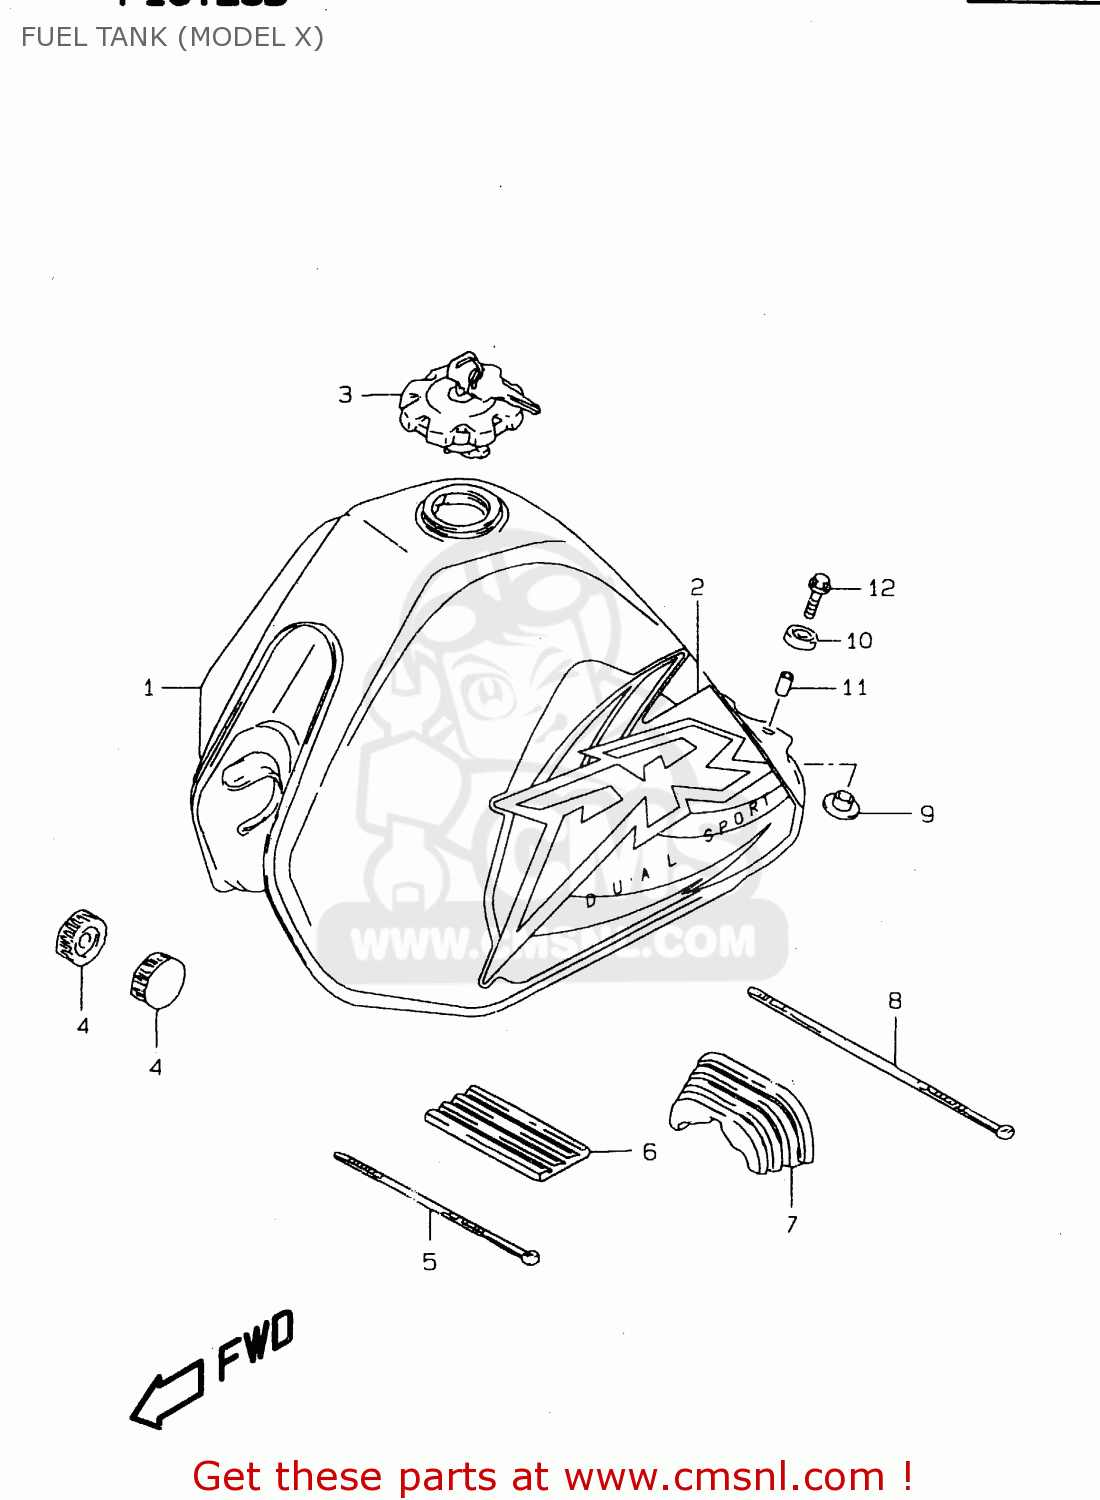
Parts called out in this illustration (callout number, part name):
1	TANK ASSEMBLY,FUEL
2	TAPE SET,FUEL TANK
3	CAP SET,FUEL TANK
4	CUSHION
5	CLAMP(L:250)
6	CUSHION,FUEL TANK UPR FR
7	CUSHION,FUEL TANK RR
8	CLAMP(L:300)
9	CUSHION
10	CUSHION
11	SPACER(6.5X9X18)
12	BOLT
